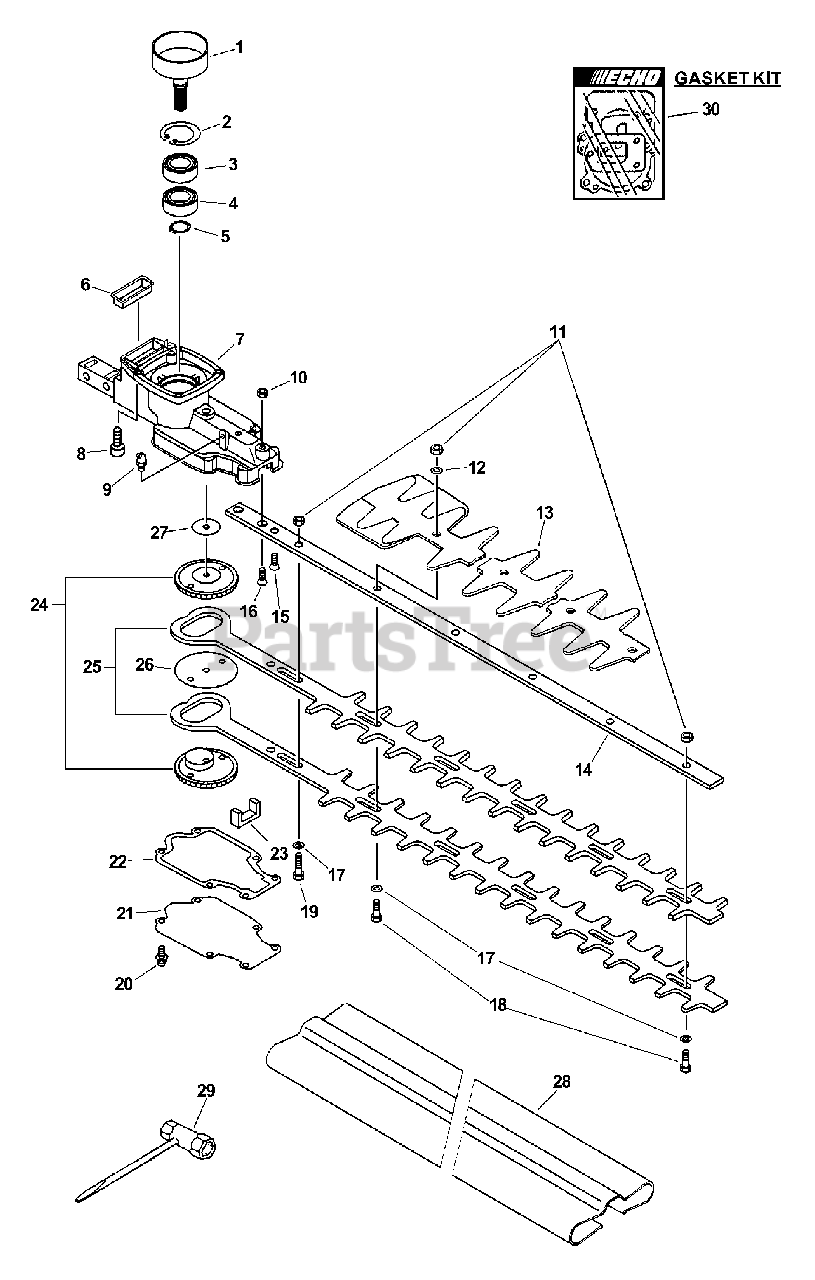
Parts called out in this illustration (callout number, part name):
1	DRUM, CLUTCH
2	RING, RETAINING - 35
3	BEARING, BALL - 6202
4	BEARING, BALL - 6202
5	RING, RETAINING - 14
6	CUSHION, FUEL TANK
7	CASE, GEAR
8	SCREW - 4X16
9	FITTING, GREASE
10	LOCKNUT - 6
11	LOCKNUT - 6
12	WASHER - 6
13	SUPPORT, BLADE
14	SUPPORT, BLADE
15	SCREW - 5X30
16	SCREW - 6X30
17	WASHER - 6
18	BOLT - 6X18
19	BOLT - 6X35
20	SCREW - 4X12
21	LID, GEAR CASE
22	GASKET, GEAR CASE
23	SEAL, FELT
24	GEAR - SPUR
25	BLADE - 20" (50cm)
28	COVER, BLADE
29	T-WRENCH - 13X19mm
30	GASKET KIT
